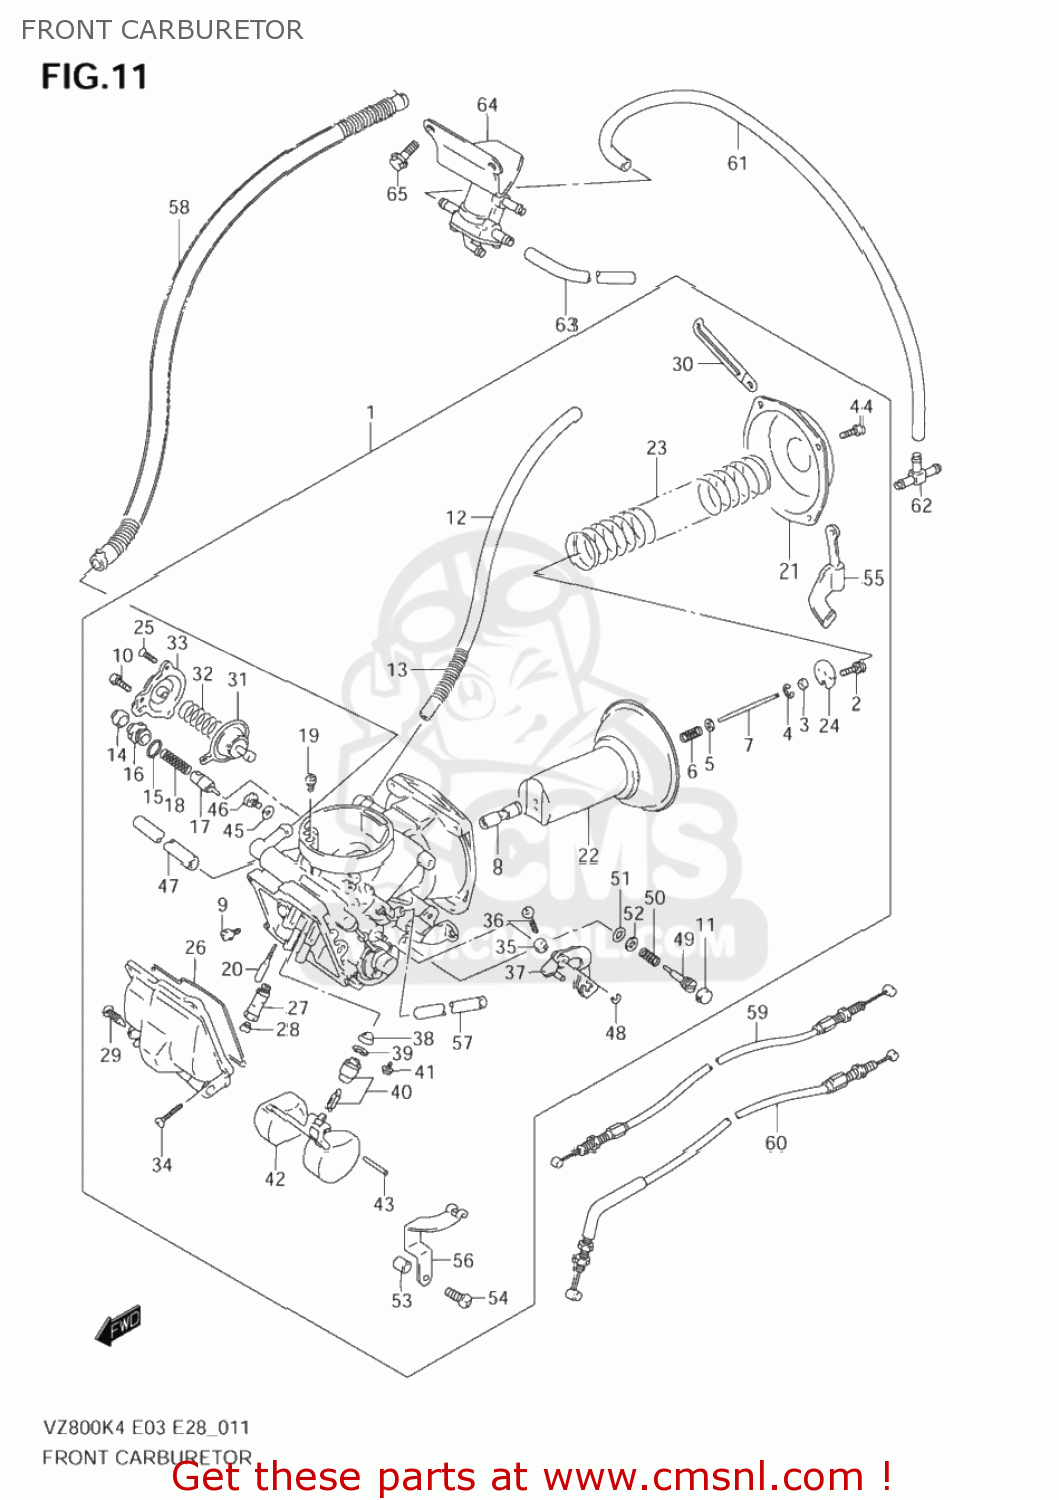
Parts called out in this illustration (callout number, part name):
1	CARBURETOR ASSY,FR
2	SCREW
3	RING
4	CLIP
5	WASHER
6	SPRING
7	NEEDLE,JET(5C43-1)
8	JET,NEEDLE(P-4M)
9	SCREW
10	SCREW
11	PLUG
12	HOSE
13	SPRING
14	CAP
15	O RING
16	HOLDER,GUIDE
17	PLUNGER,STARTER
18	SPRING
19	JET,AIR(65)
20	JET,PILOT(40)
21	COVER,DIAPHRAGM
22	DIAPHRAGM,CARBURETOR
23	SPRING,DIAPHRAGM
24	PLATE
25	SCREW,UPPER
26	O RING,FLOAT CHAMBER
27	HOLDER,MAIN JET
28	JET,MAIN(90)
29	SCREW,DRAIN
30	CLAMP(L:65)
31	DIAPHRAGM ASSY
32	SPRING
33	COVER
34	SCREW
35	NUT
36	SCREW
37	LEVER ASSY
38	FILTER
39	O RING,NEEDLE VALVE SEAT
40	VALVE ASSY,NEEDLE
41	SCREW
42	FLOAT
43	PIN,FLOAT
44	SCREW
45	GASKET,DRAIN PLUG (NAS)
46	SCREW(5X6)
47	HOSE
48	E RING
49	SCREW,PILOT
50	SPRING
51	O RING,PILOT AIR SCREW
52	WASHER
53	RING
54	SCREW
55	BRACKET
56	BRACKET
57	HOSE ASSY(5X8X125)
58	HOSE ASSY
59	CABLE,IDLE SYNCRO
60	CABLE,THROTTLE RETURN F-R
61	HOSE
62	NIPPLE
63	HOSE(5X10X600)
64	VALVE,AIR VENT
65	BOLT
